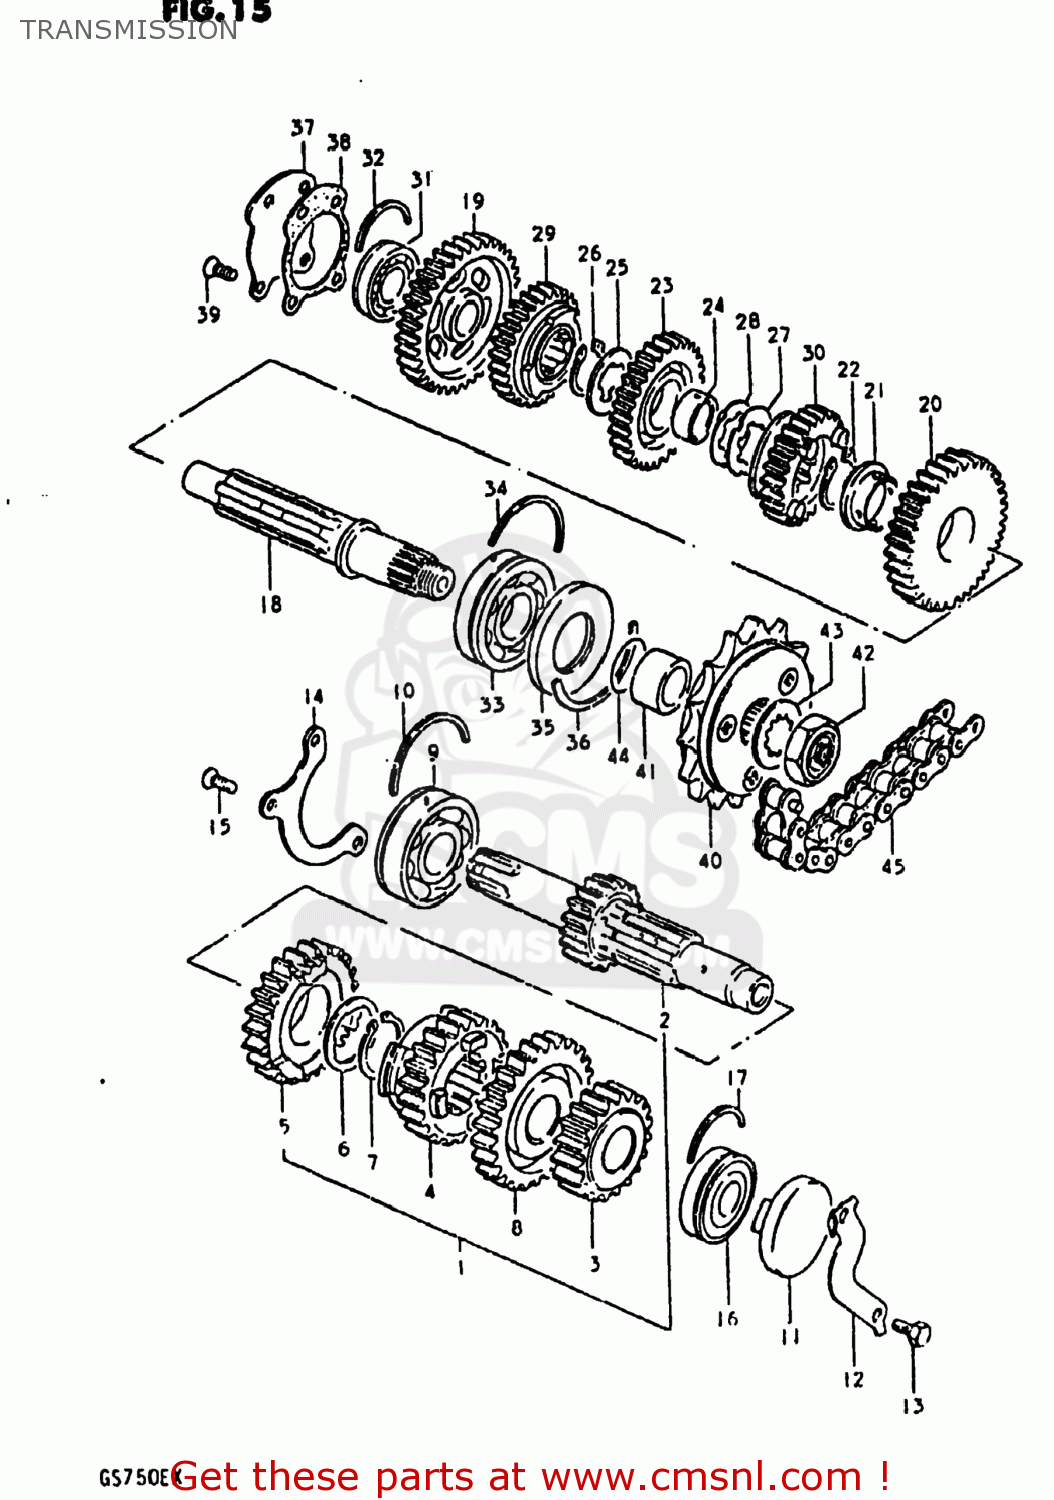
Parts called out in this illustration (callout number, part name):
1	SHAFT ASSEMBLY,COUNTER
2	SHAFT,COUNTER
3	GEAR,SECOND DRIVE
4	GEAR,THIRD DRIVE
5	GEAR,FOURTH DRIVE
6	WASHER,LOCK
7	CIRCLIP
8	GEAR,FIFTH DRIVE
9	BEARING(25X62X17)
10	C-RING
11	PLUG
12	RETAINER,CL PUSH ROD OIL SEAL
13	BOLT
14	RETAINER,CNTR SHAFT BEARING
15	SCREW
16	BEARING(20X47X14)
17	C RING
18	SHAFT,DRIVE
19	GEAR,FIRST DRIVEN
20	GEAR,SECOND DRIVEN
21	BUSH(28X32X2)
22	CIRCLIP
23	GEAR,THIRD DRIVEN
24	BUSH,3RD DRIVEN GEAR
25	WASHER,LOCK
26	CIRCLIP
27	WASHER,LOCK
28	WASHER
29	GEAR,FOURTH DRIVEN
30	GEAR,FIFTH DRIVEN
31	BEARING
32	C RING
33	BEARING(25X62X17)
34	C-RING
35	SEAL,OIL(32X62X7)
36	C RING
37	PLATE,DRIVE SHAFT
38	GASKET,DRIVESHAFT PLATE (MCA)
39	SCREW
40	SPROCKET,ENGINE
41	SPACER(25X32X18.6)
42	NUT
43	WASHER
44	O RING(D:1,ID:24.5)
45	CHAIN ASSEMBLY,DRIVE
